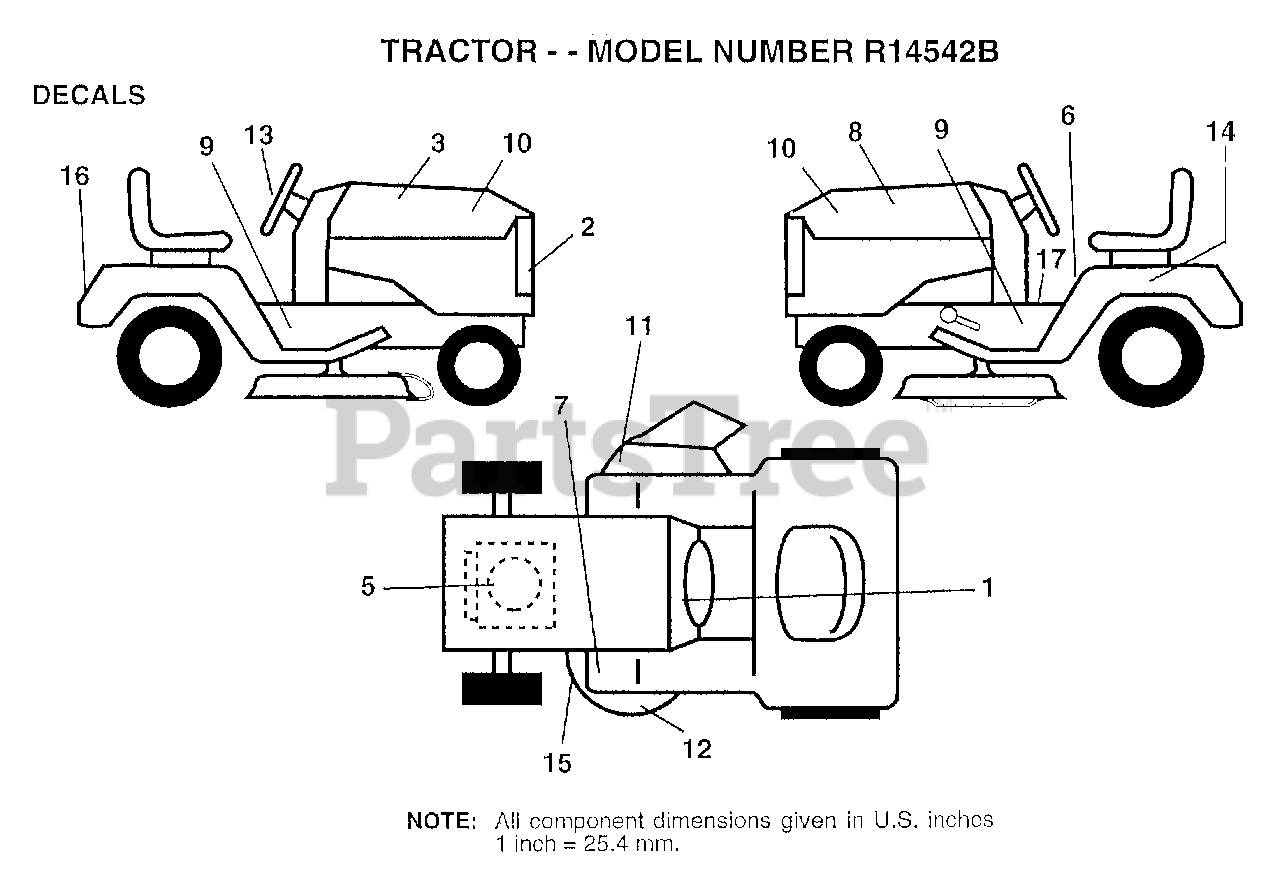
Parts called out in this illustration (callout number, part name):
1	DECAL.INSTR.FRENC
2	GRILL DECAL
3	DECAL.HD.RH.RALLY
5	DECAL, ENGINE
6	DECAL.CAUT.ENG/FR
7	DECAL T
8	DECAL.HD.LH.RALLY
9	CHASSIS DECAL
10	DECAL.INS.HD.RALL
11	"DECAL, WARNING"
13	"DECAL,STR WHL"
14	DECAL.BATRY.3-3908
15	DECAL
16	FENDER DECAL
17	DECAL BRAK PARK
